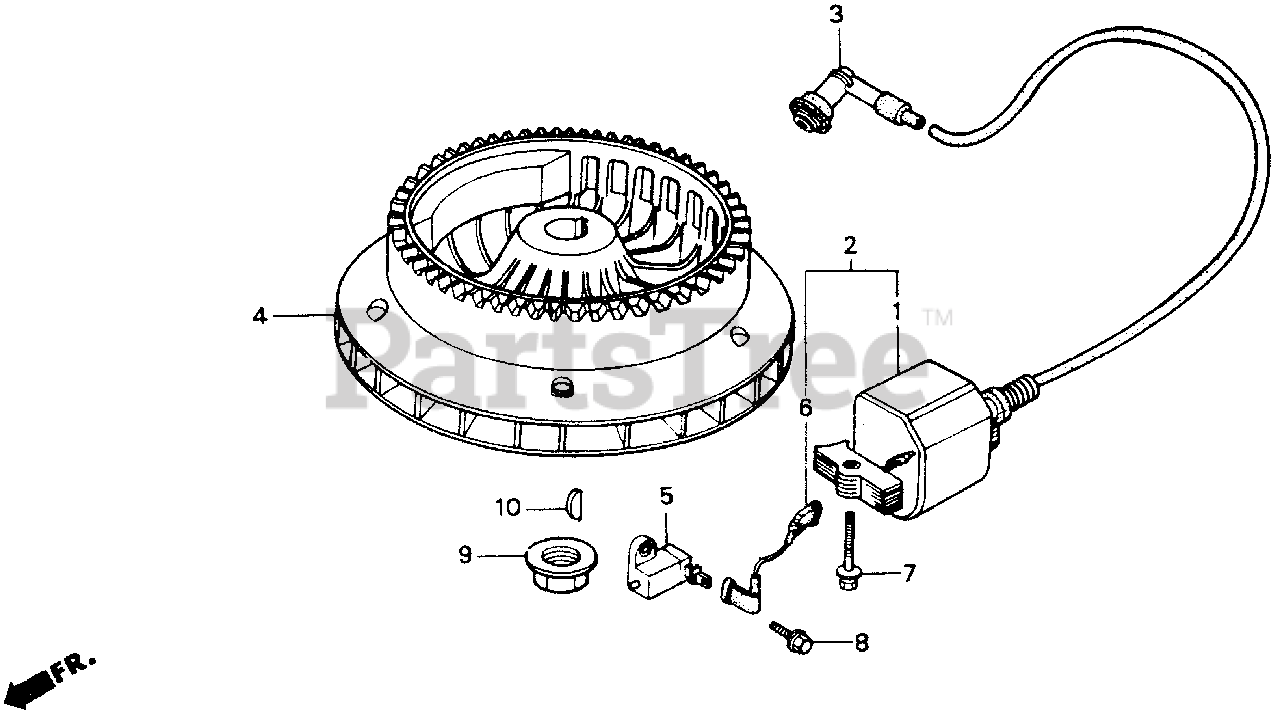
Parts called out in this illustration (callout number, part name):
1	COIL ASSY., IGNITION
2	COIL ASSY., IGNITION
3	CAP ASSY., NOISE SUPPRESSOR
4	FLYWHEEL ASSY.
5	SWITCH ASSY., ENGINE
6	WIRE, SWITCH (NOT AVAILABLE)
7	BOLT, FLANGE (6X28) (CT200)
7	BOLT, FLANGE (6X32) (CT200)
7	BOLT, FLANGE (6X28)
8	BOLT, FLANGE (6X16) (CT200)
9	NUT, FLANGE (16MM)
10	KEY, SPECIAL WOODRUFF (25X18)
10	KEY, WOODRUFF (25X18)
